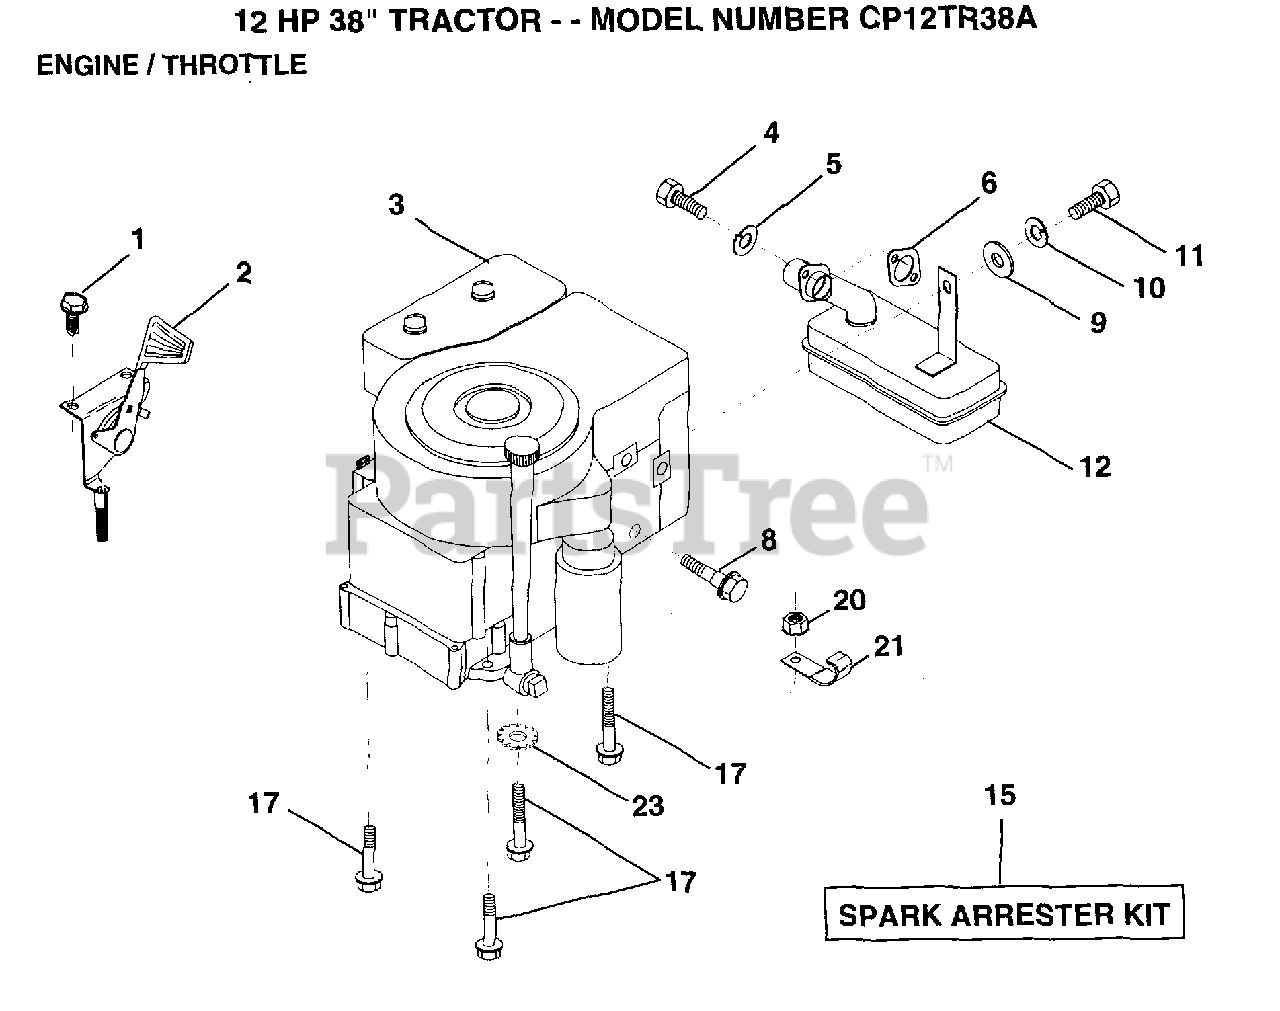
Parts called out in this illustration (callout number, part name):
1	SCREW.1/4-20X1/2
2	"CONTROL,THROTTLE"
4	SCREW
5	LOCKWASHER
8	SHOULDER BOLT ST
10	LOCKWASHER
11	BOLT LT
17	SCREW LT
20	NUT
21	CLIP T
23	LOCKWASHER
